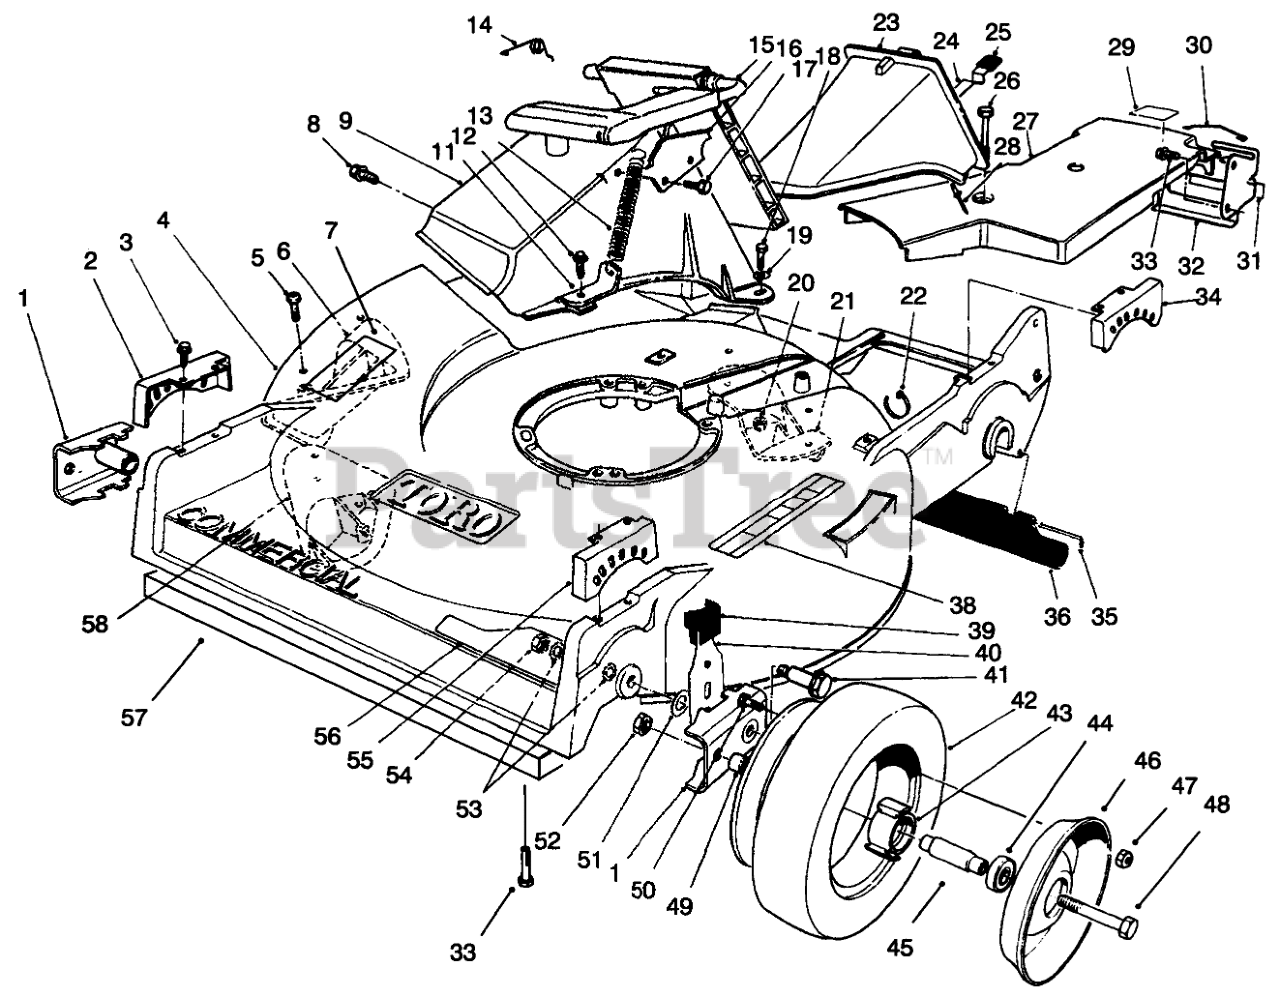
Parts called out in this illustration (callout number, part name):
1	ARM-PIVOT, FRONT
2	QUADRANT-FRONT, RH
3	SCREW-HWHTF
4	Housing-Commercial (Incl. Ref. #5-7, 21, 38, & 58)
5	SCREW-PPH
6	KICKER-RH
7	DECAL-DANGER
8	SCREW AND WASHER ASM
9	TUNNEL-DISCHARGE
11	BRACKET-SPRING
12	SCREW-HWH
13	SPRING-DOOR
14	RETAINER-DOOR
15	DOOR ASSEMBLY
16	DOOR LATCH PLATE
17	SCREW-PLASTITE
18	SCREW-HH
19	WASHER-FLAT
20	NUT-LOCK, NI
21	KICKER-REAR
22	TIE-CABLE
23	Plug Assembly (Incl. Ref. #24, 25, & 28)
24	LATCH-PLUG, DISCHARGE
25	GRIP-LATCH
26	SCREW-HHFTF
27	COVER-BELT
28	RIVET-HEAD, FLAT
29	DECAL-GREASE
30	RETAINER-CABLE
31	DECAL-POSITION, GEAR
32	BRACKET-ADJUSTMENT, TRACTION
33	SCREW-HWHTF
34	QUADRANT-REAR, LH
35	ROD-SHIELD
36	SHIELD-TRAILING
38	DECAL-DANGER
39	KNOB-ARM
40	FRONT SPRING ARM ASM
41	BOLT-WHEEL
43	HUB-BEARING
44	BEARING-WHEEL
45	SPACER-BEARING
46	Wheel-Half
47	NUT-LOCK, NI
48	SCREW-HH
49	SPACER-WHEEL
50	SCREW-HH
51	WASHER-THRUST
52	NUT-LOCK, CONE
53	WASHER
54	NUT-LOCK
55	QUADRANT-FRONT, LH
56	DECAL - DECK
57	Shield-front
58	KICKER-FRONT
